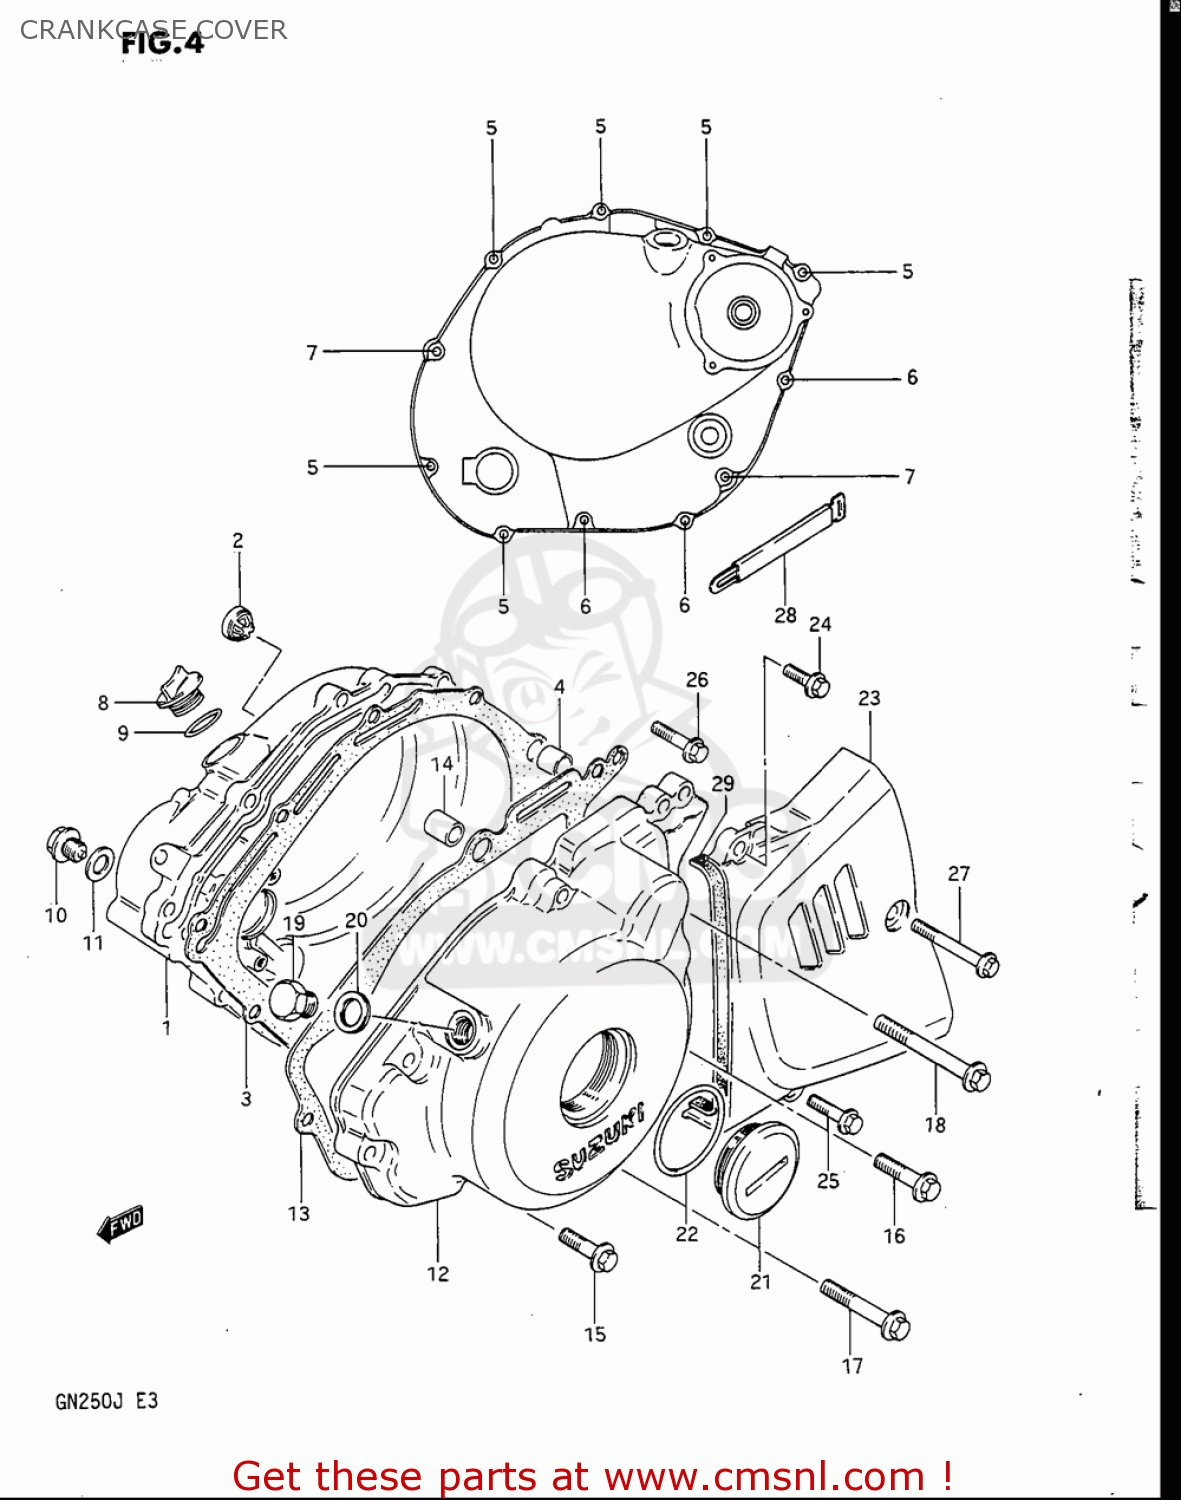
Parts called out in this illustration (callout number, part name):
1	COVER,CLUTCH
2	LENS,OIL LEVEL CHECK
3	GASKET,CLUTCH COVER (NAS)
4	PIN
5	BOLT
6	BOLT
7	BOLT
8	PLUG(20X10)
9	O RING(D:3.1,ID:16.8)
10	PLUG(14X12)
11	GASKET(14X19.2X2) (NAS)
12	COVER,MAGNETO
13	GASKET,MAGNETO COVER (NAS)
14	PIN
15	BOLT
16	BOLT
17	BOLT
18	BOLT
19	PLUG,12X9
20	GASKET(12.1X16.2X3.7) (NAS)
21	PLUG,36X10
22	O RING(D:3.1,ID:32.7)
23	COVER,ENGINE SPROCKET
24	BOLT
25	BOLT
26	BOLT
27	BOLT
28	CLAMP
